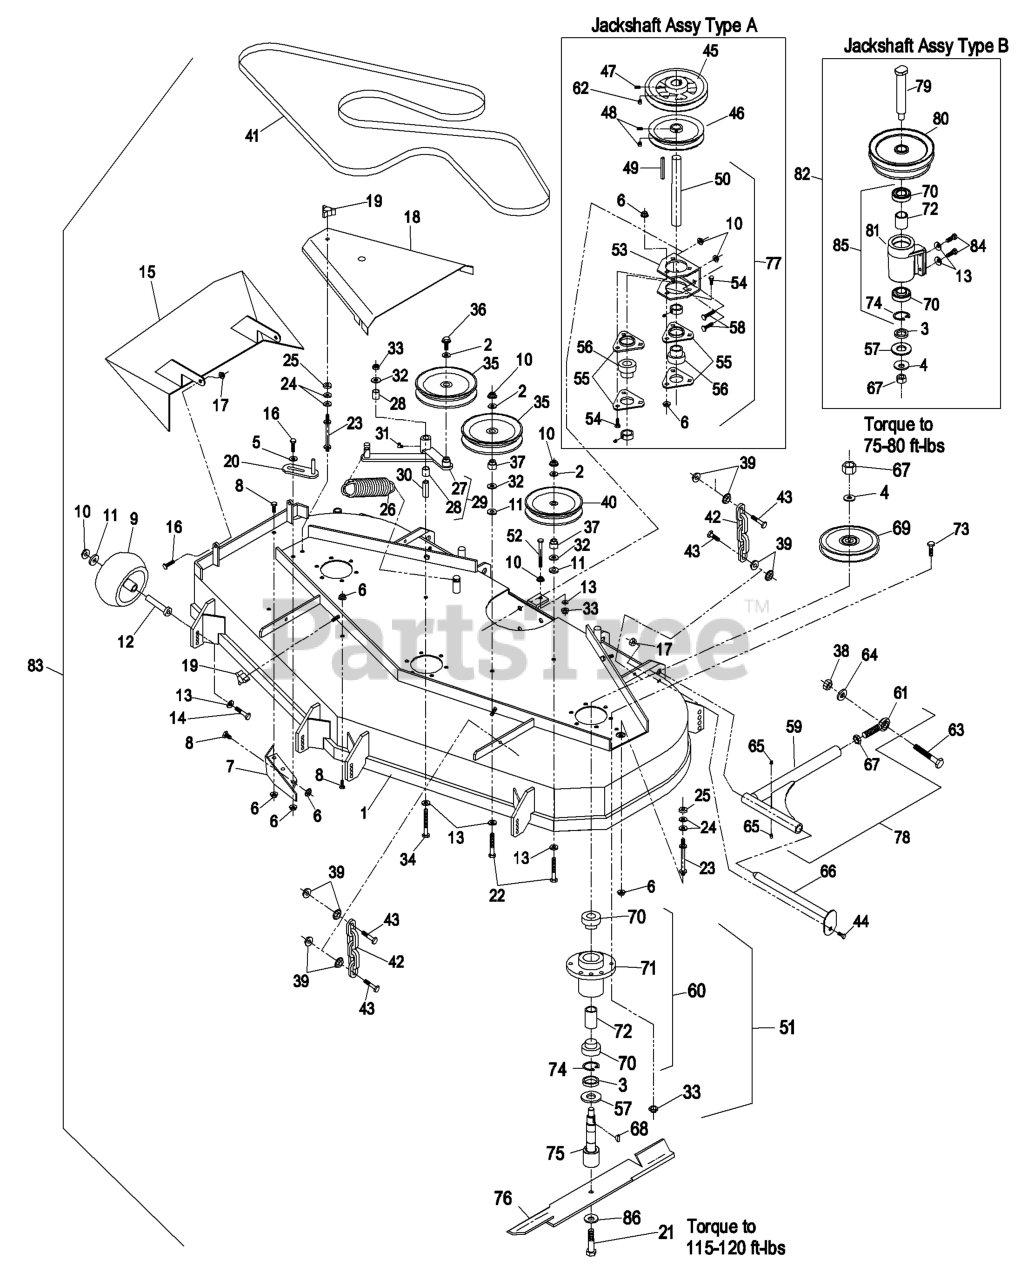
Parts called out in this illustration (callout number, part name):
1	Deck Wldmt, 52"
2	WASHER-FLAT
3	SPACER-PULLEY/BEARING
4	WASHER-SPRING
5	WASHER-SPRING
7	WLD,BAFFLE DISCHARGE
8	SCREW-HH
9	ROLLER-SCALP, ANTI
10	NUT-HHF, WHIZ
12	BUSHING-ROLLER
13	WASHER-BELLEVILLE
14	SCREW-HH
16	SCREW-HH
17	NUT-LOCK, NI
18	SHIELD,BELT 52
19	KNOB-3 PRONG
20	GUIDE-BELT
21	SCREW-CAP
22	SCREW-HH
23	STUD-SHIELD, BELT (SHORT)
24	WASHER-FLAT
28	SLEEVE-BEARING
30	BUSHING
31	FITTING-GREASE, 90 DEG
32	WASHER-FLAT
33	NUT-LOCK, NI
34	SCREW-HH
36	SCREW-HHF
37	BUSHING-IDLER
38	NUT-HEX
40	PULLEY-IDLER
41	BELT,BLADE DRIVE 52
42	CHAIN-LIFT, DECK
43	SCREW-CAP, HH
44	SCREW-HH
46	SHEAVE,SPLIT STEEL
47	SCREW-SET
48	SCREW-SET
49	KEY,MACH 1/4X1/4X2-5/8
50	JACKSHAFT,DECK DRIVE
51	ASM,SPINDLE HSG COMPLETE
52	SCREW-HH
53	BRACKET,JACKSHAFT
54	BOLT-CARR
55	HOUSING-FLANGE
56	BEARING,W/COLLAR
57	GUARD-BEARING, BOTTOM
58	SCREW-CARR
61	BALLJOINT-SPHERICAL
62	SCREW-SET
63	SCREW-HH
64	WASHER-LOCK
65	FITTING-GREASE
66	PIN-STRUT
67	NUT-HEX
68	KEY-WOODRUFF
69	SHEAVE,BLADE DRIVE
70	BEARING
72	SPACER-BEARING
73	SCREW-HH
74	RING-SNAP
77	DK DR. BRG. ASSY
78	STRUT ASM
79	JACKSHAFT
80	SHEAVE,JACKSHAFT-DOUBLE
82	ASM,JCKSHFT KIT 52 3600
83	Complete Deck Asy
84	SCREW-HH
86	WASHER-BLADE BOLT, HEAVY
